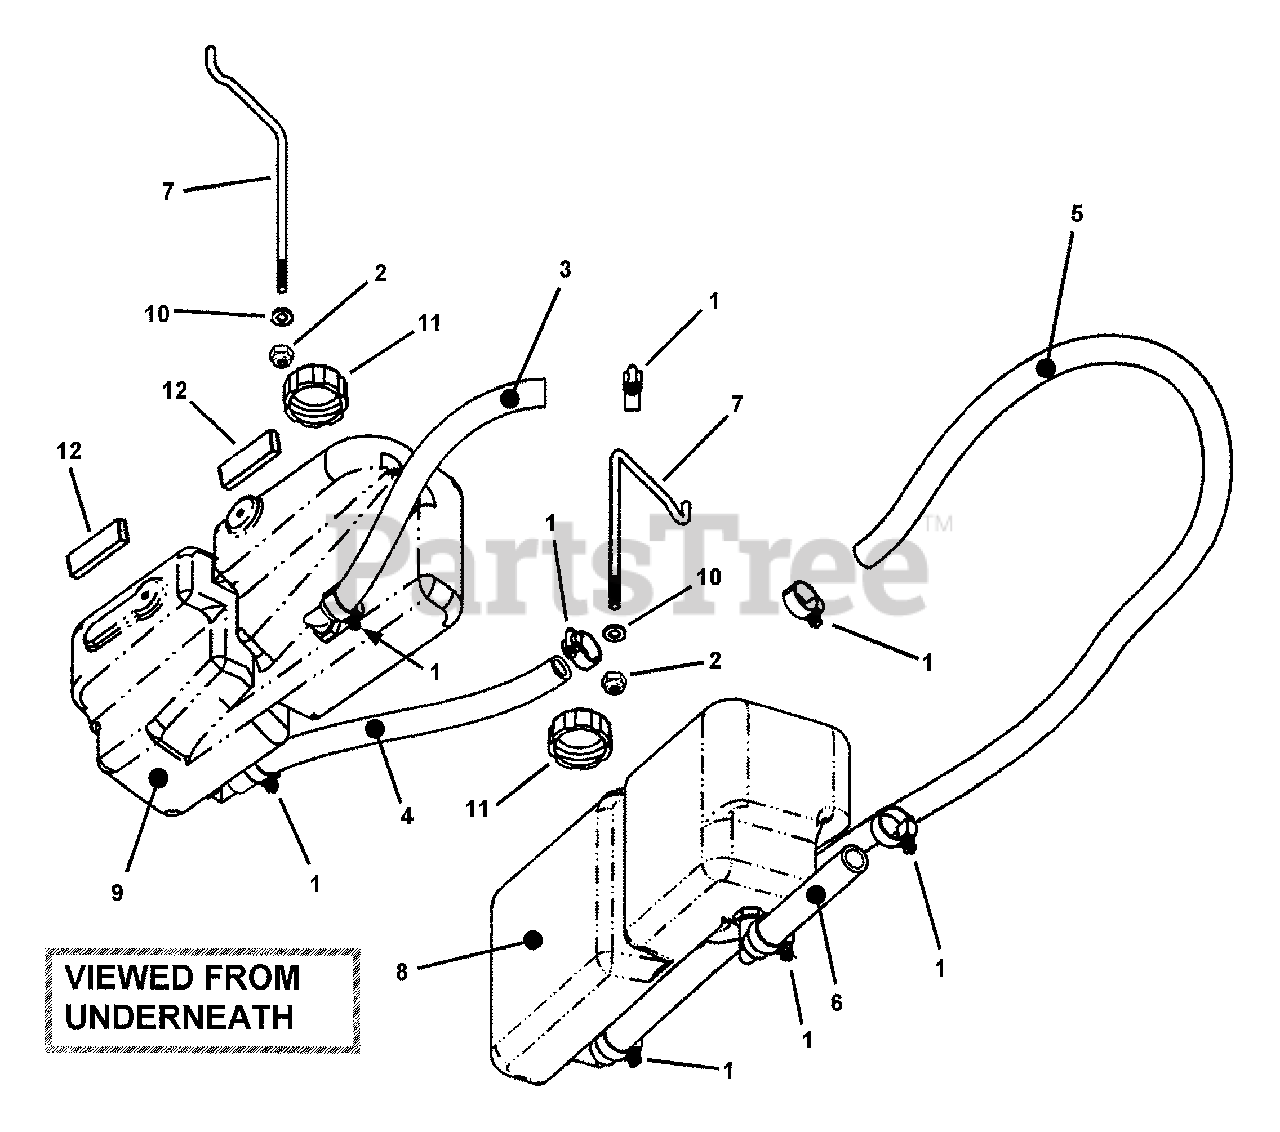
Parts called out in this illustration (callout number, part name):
1	CLAMP, Hose 13/16"
2	NUT, 5/16-18 HEX NYLON LOCK
3	HOSE, Rubber R.H.Front (.625 I.D. x 13-1/2" Long)
4	HOSE, Rubber R.H.Back (.625 I.D. x 16" Long)
5	HOSE, Rubber (.625 I.D. x 34" Long)
6	HOSE, Rubber (.625 I.D. x 6" Long)
7	BRACKET, Reservoir
8	RESERVOIR, L.H. Hydro
9	RESERVOIR, R.H. Hydro
10	WASHER, 11/32 I.D. x 11/16" O.D.
11	CAP, Reservoir
